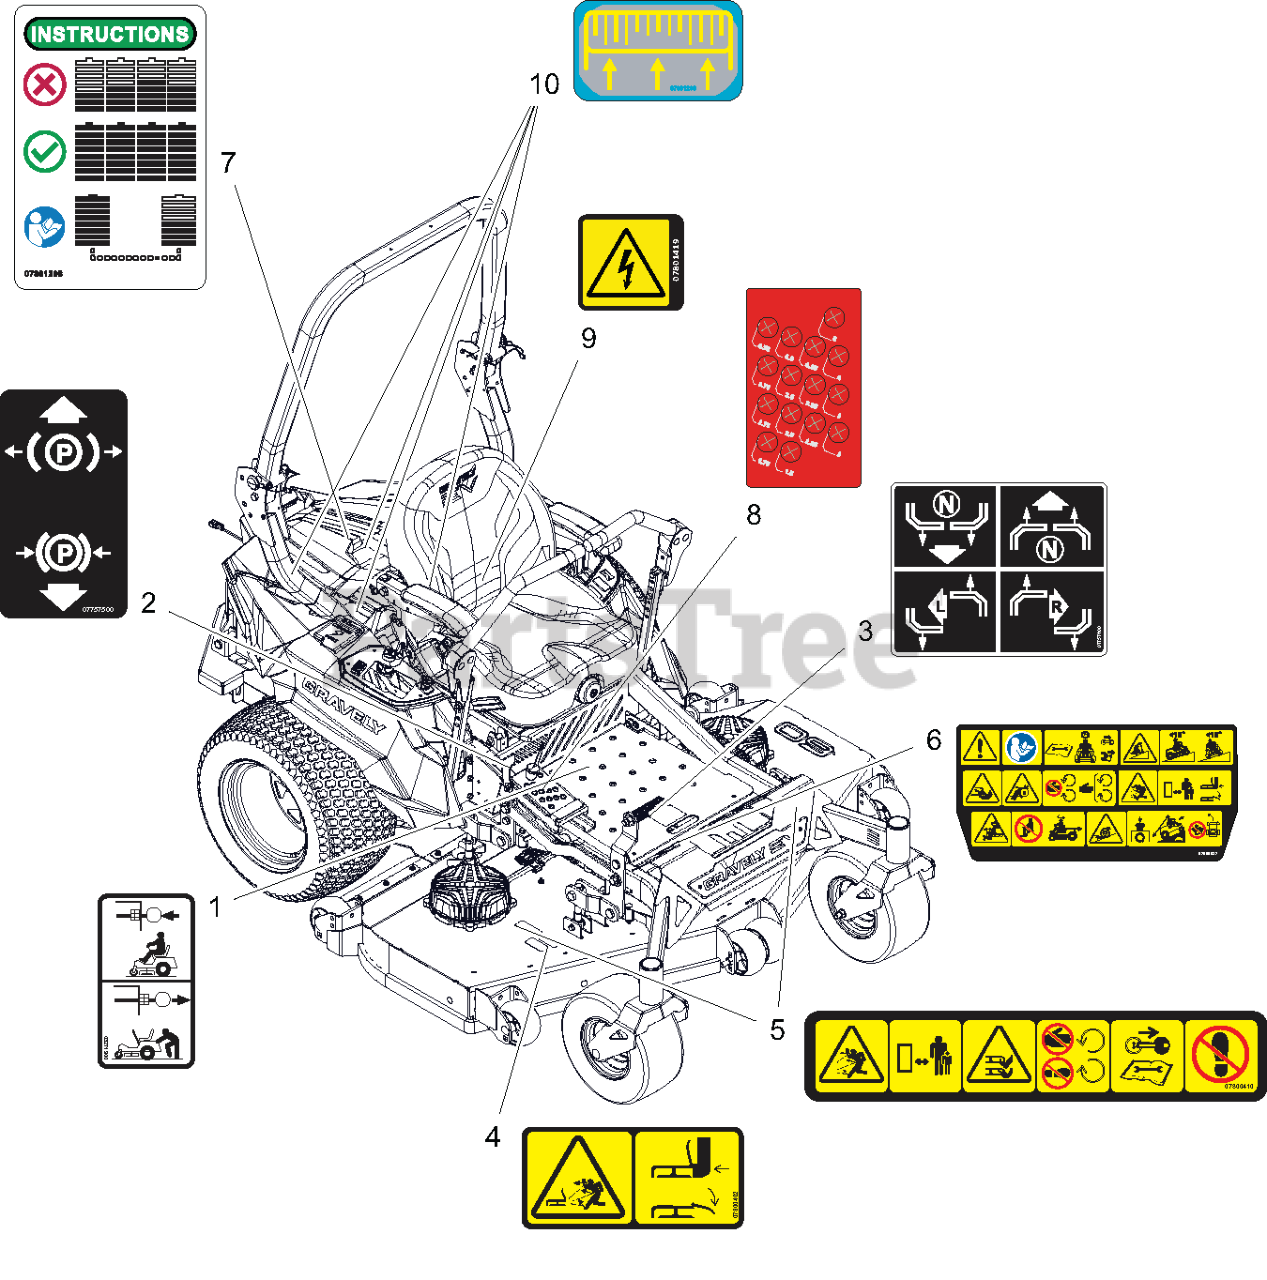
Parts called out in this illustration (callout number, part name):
1	DECAL, TRANSMISSION DISCONNECT
2	DECAL, PARKING BRAKE LEVER
3	DECAL, INSTRUCTIONAL-STEERING
4	DECAL, SAFETY - DECK GUARDING
5	DECAL, DECK SAFETY
6	DECAL, MAIN SAFETY
7	DECAL, BATTERY BALANCE
8	DECAL, HEIGHT OF CUT
9	DECAL, SAFETY - DANGER
10	DECAL, BATTERY INSTALL DIRECTION
